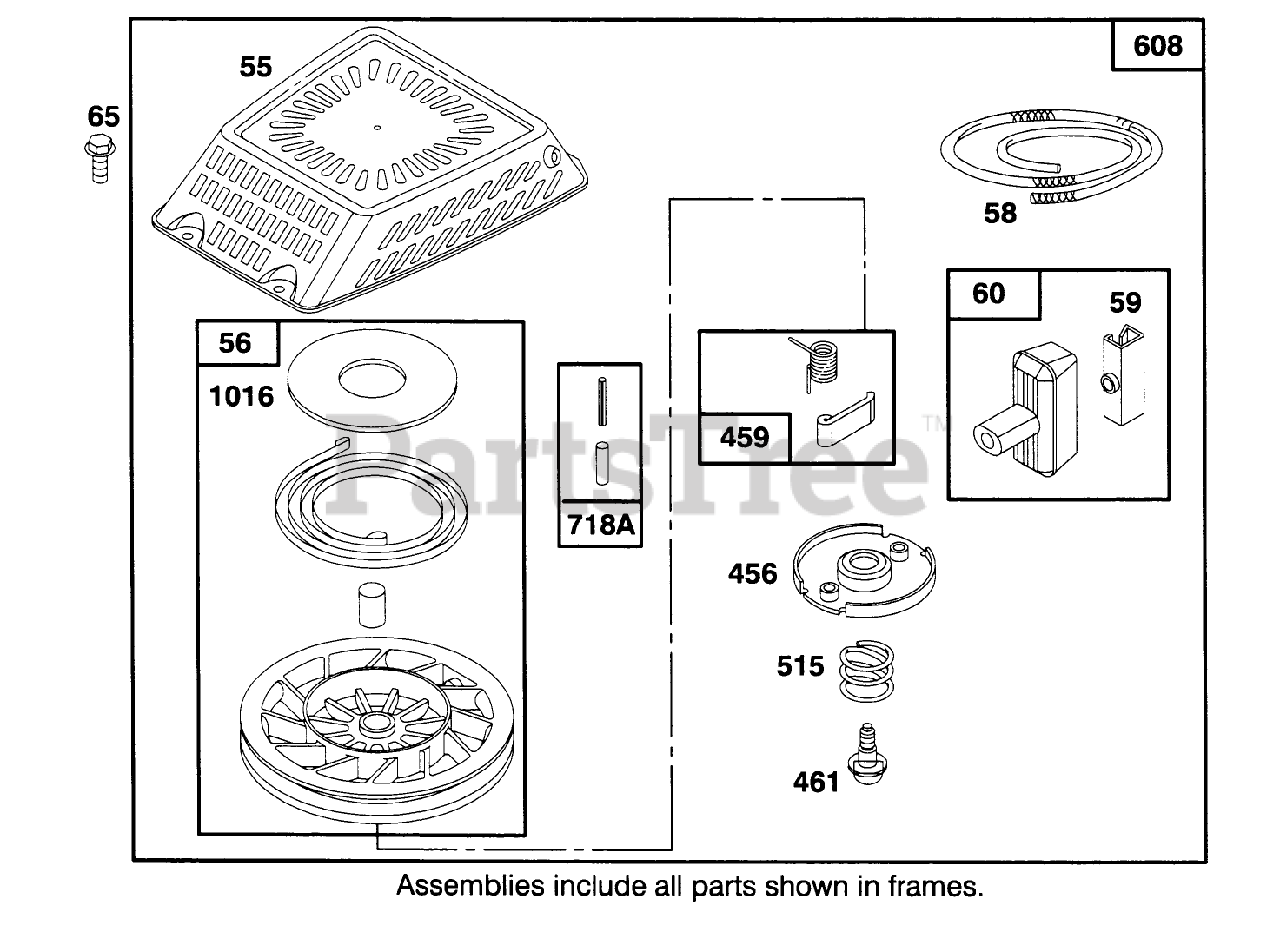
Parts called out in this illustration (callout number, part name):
60	HANDLE-REWIND STARTER
456	RETAINER - SPRING
515	SPRING - RETAINER
